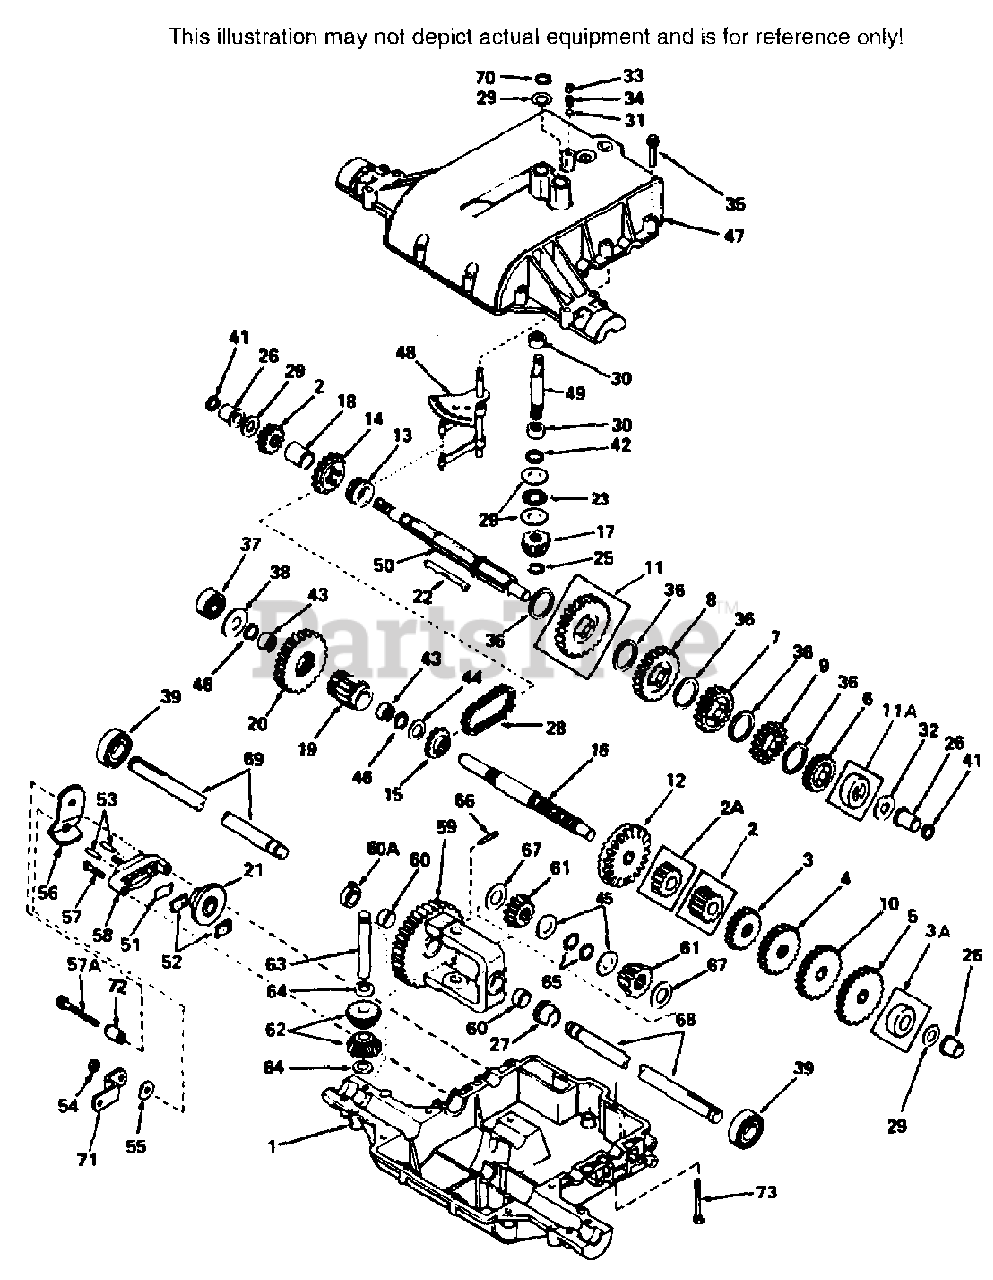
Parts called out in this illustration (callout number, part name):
1	CASE, TRANSAXLE
2	GEAR, SPUR(15 TEETH)
4	GEAR, SPUR(20 TEETH)
5	GEAR, SPUR(28 TEETH)
6	GEAR, SPUR(22 TEETH)
7	GEAR, SPUR(30 TEETH)
8	GEAR, SPUR(35 TEETH)
9	GEAR, SPUR(25 TEETH)
11	GEAR, SPUR(37 TEETH)
12	GEAR, BEVEL(42 TEETH)
13	COLLAR, SHIFT
14	SPROCKET(18 TEETH)
15	SPROCKET(9 TEETH)
16	SHAFT, COUNTER
17	BEVEL PINION, INPUT
18	SPACER
19	PINION, OUTPUT
20	GEAR, OUTPUT
21	DISK, BRAKE
23	BEARING, THRUST
25	RING, RETAINING
28	CHAIN, ROLLER(NO. 41 CHAIN, 24 LINKS)
29	WASHER, THRUST
30	BEARING, NEEDLE
31	BALL, STEEL
32	WASHER, THRUST
33	SCREW, SET, 3/8-16 X 3/8
34	SPRING
35	SCREW, HEX HD. THREAD FORMING,
36	WASHER, THRUST
37	BEARING, BALL
38	WASHER, FLAT
39	BEARING, BALL
41	RING, SQUARE CUT
42	RING, SQUARE CUT
43	BEARING, NEEDLE
44	WASHER, FLAT
45	WASHER
46	RING, SQUARE CUT
47	COVER, TRANSAXLE
48	ROD & FORK ASSEMBLY, SHIFT
49	SHAFT, INPUT
50	SHAFT BRAKE
51	PLATE, BRAKE PAD
52	PAD, BRAKE
53	PIN, DOWEL
54	LOCKNUT, 5/16-24
55	WASHER, FLAT
56	LEVER, BRAKE
57	SCREW, HEX HD. THREAD FORMING,
57A	SCREW, HEX HD. THREAD FORMING,
58	HOLDER, BRAKE PAD
60	BUSHING
60A	BUSHING
61	GEAR, BEVEL
62	PINION, BEVEL
63	PIN, DRIVE
64	WASHER, THRUST
65	RING, RETAINING
66	PIN, ROLL
67	WASHER, THRUST
70	RING, RETAINING
71	BRACKET, BRAKE LEVER
72	SPACER
73	SPECIAL BOLT
